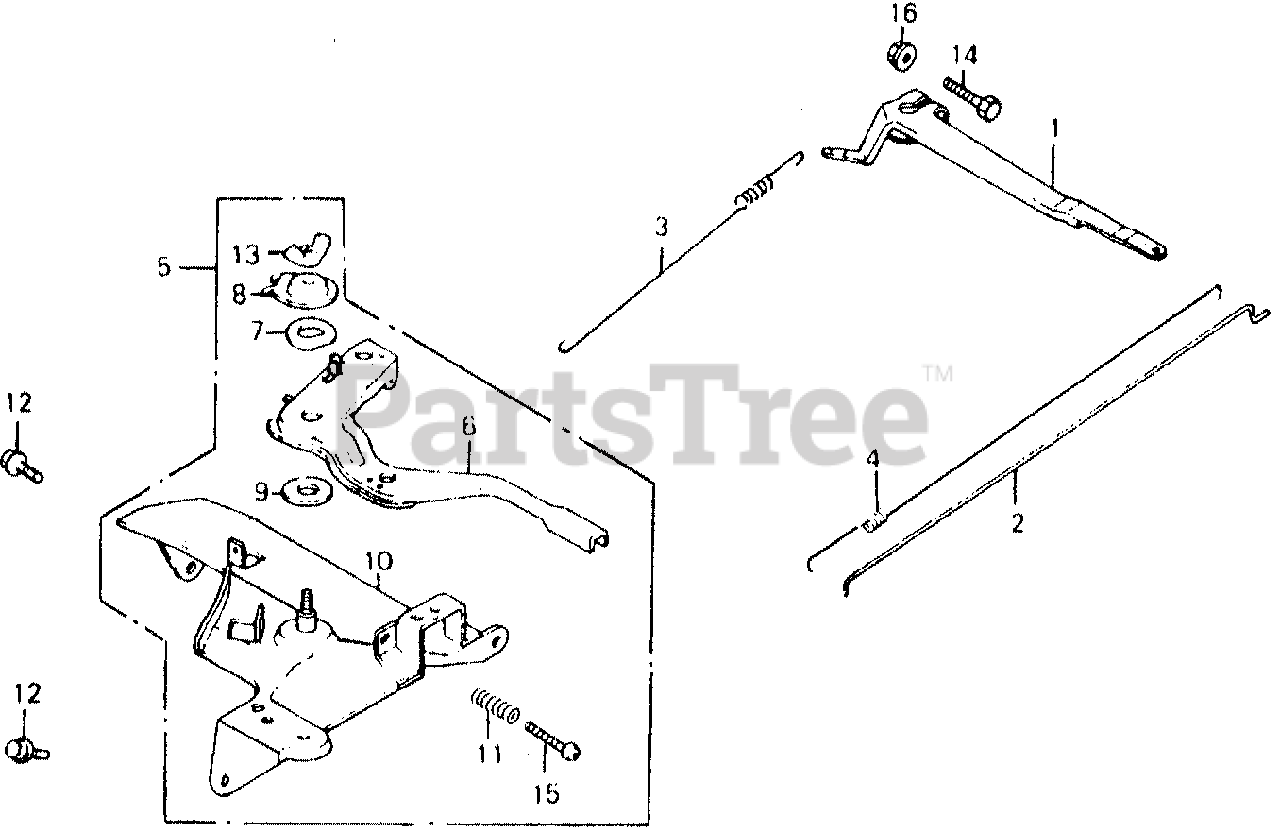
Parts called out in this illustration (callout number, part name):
1	ARM, GOVERNOR
2	ROD, GOVERNOR
3	SPRING, GOVERNOR
4	SPRING, THROTTLE RETURN
5	CONTROL ASSY.
6	LEVER, CONTROL
7	SPRING, LEVER
8	WASHER, CONTROL LEVER
9	SPACER, CONTROL LEVER
10	BASE, CONTROL
11	SPRING, CONTROL ADJUSTING
12	BOLT, FLANGE (6X12) (CT200)
13	WINGNUT (6MM)
14	BOLT, GOVERNOR ARM
14	BOLT, HEX. (6X22)
15	SCREW, PAN (5X28)
16	NUT, FLANGE (6MM)
